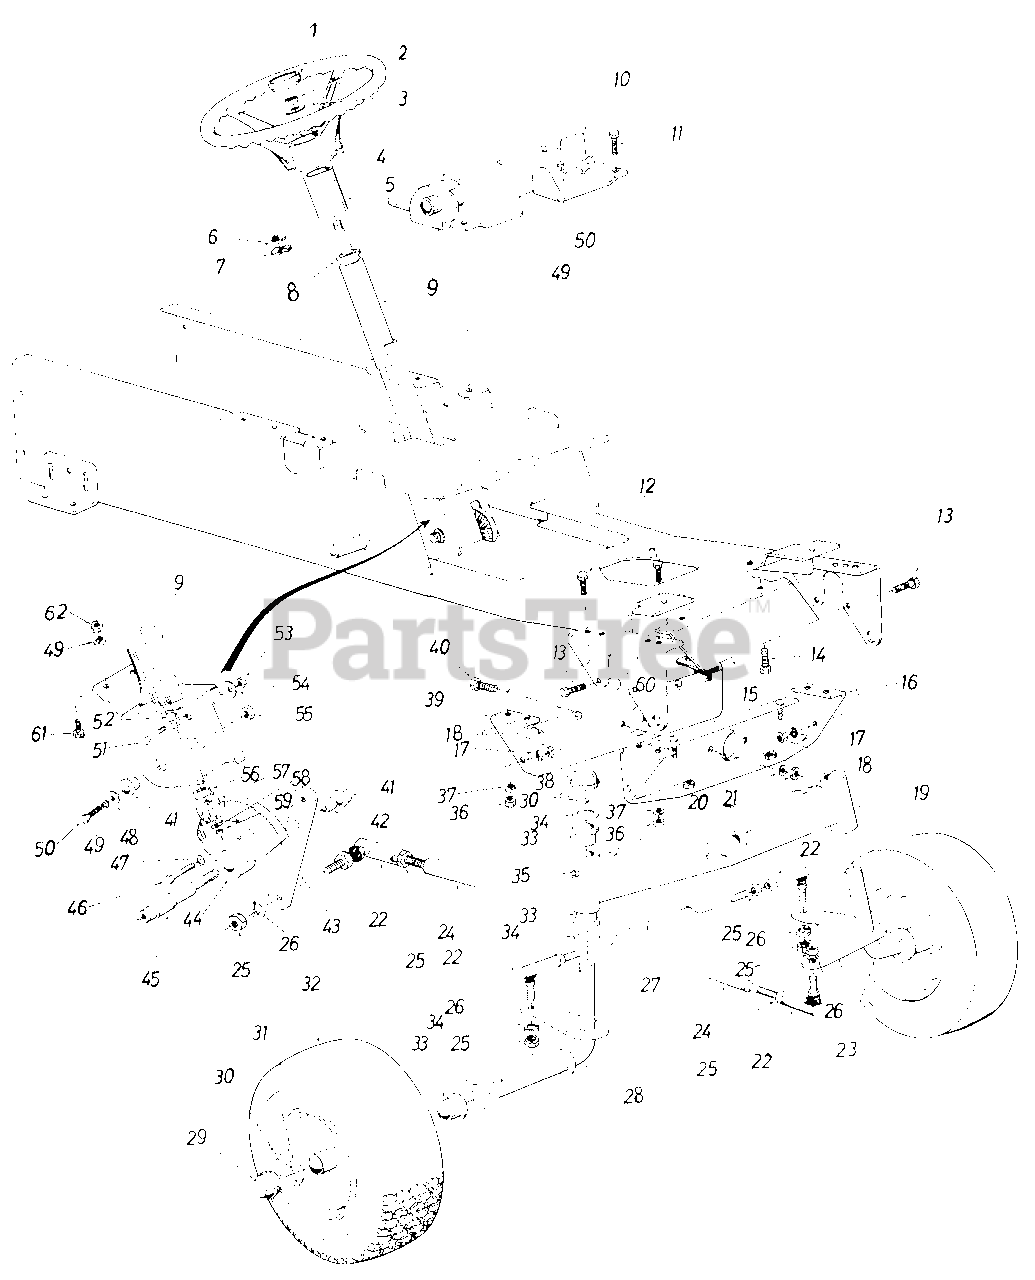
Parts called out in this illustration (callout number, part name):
1	Steering Wheel Cap
2	Hex Cent. L-Nut 5/16-18 Thd.
3	Bell-Wash.
4	Steering Wheel
5	Steering Tube-Outer
6	Double"D" Fl-Wash.
7	Wave Wash. .660 I.D. x .88 O.D.
8	Ball Brg. .63 I.D. x 1.38 O.D.
10	Dash Panel Base Plate Ass'y.
11	Hex Self-Tap Scr. 3/8-16 x .751' Lg.
12	Hex Scr. 3/8-16 x 1.50" Lg.
13	Hex Scr. 3/8-16 x 1.00" Lg.
14	Hex Wash. S.F. Tap Scr. 3/8-16 x 1.25" Lg.
15	Dust Shield
18	Hex Nut 3/8-16 Thd.
19	Pivot Bar Ass'y.
20	Bell-Wash. 3/8" Scr.
21	Hex Cent. L-Nut 3/8-16 Thd.
22	Drag Link End
23	Axle Ass'y.-L.H.
24	Drag Link
25	Hex Nut 1/2-20 Thd.
26	L-Wash. 1/2" Scr.
27	Tie Rod
28	Axle Ass'y.-R.H.
29	Dust Cover
30	Cotter Pin 3/16" Dia. x 1.50" Lg.*
31	Fl-Wash. 1.00" I.D. x 1.62" O.D.
33	Flange Brg. 1.00" I.D.
34	Fl-Wash. 1.00" I.D. x 1.62" O.D.
35	Grease Fitting
36	Hex Nut 3/8-16 Thd.
37	L-Wash. 3/8" Scr.
38	Dust Cover
40	Hex Scr. 3/8-16 x 2.50" Lg.
41	Flange Brg. w/Flats .753 I.D.
42	Steering Gear Shaft Spacer
43	Steering Arm
44	Bevel Gear
45	Steering Gear Shaft
46	Hex Scr. 3/8-16 x 1.50" Lg.
47	L-Wash. 3/8" Scr.
48	Fl-Wash. .406 I.D. x 1.25" O.D.
49	L-Wash. 3/8" Scr.
50	Hex Scr. 3/8-16 x .75" Lg.
51	Nylon Hex Scr. 3/8-16 x 1.25" Lg.
52	Steering Shaft
53	Hex Jam Nut 3/8-16 Thd.
54	Bell-Wash. .400 I.D. x 1.13 O.D.
55	Hex Ins. L-Nut 1/2-20 Thd.
56	Hex Flange Brg. .630 I.D.
57	Pinion Gear
58	Fl-Wash. 3/8" Dia.
59	Hex Cent. L-Nut 5/16-24 Thd.
62	Hex Nut 3/8-24 Thd.
